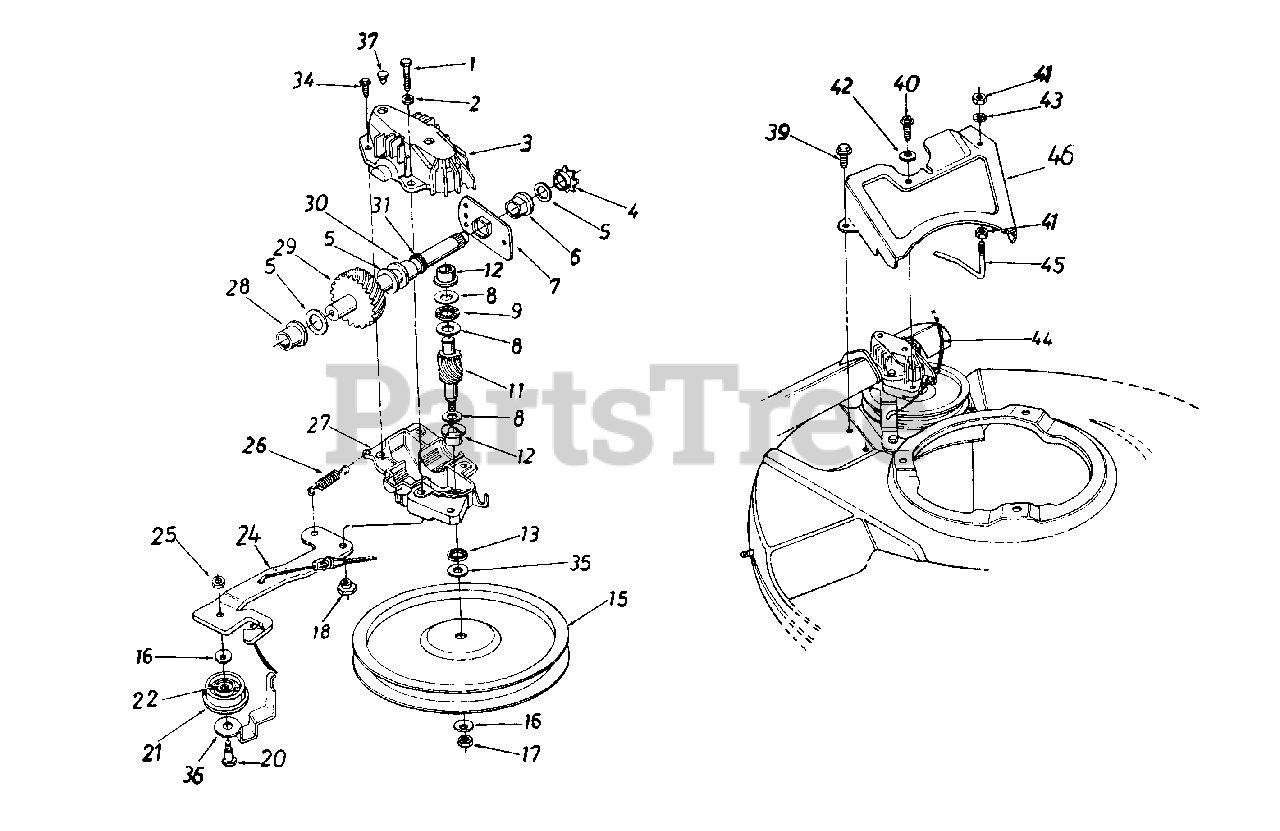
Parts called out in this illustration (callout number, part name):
1	Hex Bolt w/Patch 1/4-20 x 1.25"
2	L-Wash. 1/4" I.D.
3	Upper Hsg. Half
4	#48 Sprocket 7 Tooth x 1/2 Pitch
5	Fl-Wash. 5/8" I.D. x .030
6	Hex Flange Brg. .631" I.D.
8	Thrust Wash. .382" I.D. x .70" O.D.
9	Thrust Brg .375" I.D. x .812" O.D.
11	11 Tooth Helical Gear
12	Flange Bearing
13	Oil Seal
15	Fl-Pulley 5.06" I.D.
16	Bell-Wash. .265" I.D. x .75"
17	Hex Nut 1/4-28 L.H. Thd.
18	Shld. Spacer .375" Dia. x .170
20	Shld. Bolt .375" Dia. x .40"
21	Fl-Idler Plastic 1.50" Dia.
22	Needle Brg. .375" x .31"
24	Idler Brk't. Ass'y
25	Hex Patch L-Nut 1/4-28 Thd.
26	Extension Spring 1.12" Lg.
27	Lower Hsg. Half
28	Flange Bearing .56 Dia.
29	Shaft Ass'y.
30	Flange Bearing .629 Dia.
31	Oil Seal .625 Dia.
34	Hex B-Tap Scr. #10-16 x .75
35	Hex Washer .26" x .88"
36	Transmission Belt Keeper
37	Plug 1/4 x .437"
39	Hex AB-Tap Scr. 1/4 x .50" Lg.
40	Hex B-Tap Scr. 1/4 x .62" Lg.
41	Hex Nut 1/4-20 Thd.
42	Bell-Wash. .265" I.D. x .75"
43	L-Wash. 1/4" I.D.
44	S.P. Cable - 48" Lg.
45	S.P. Belt Guard
